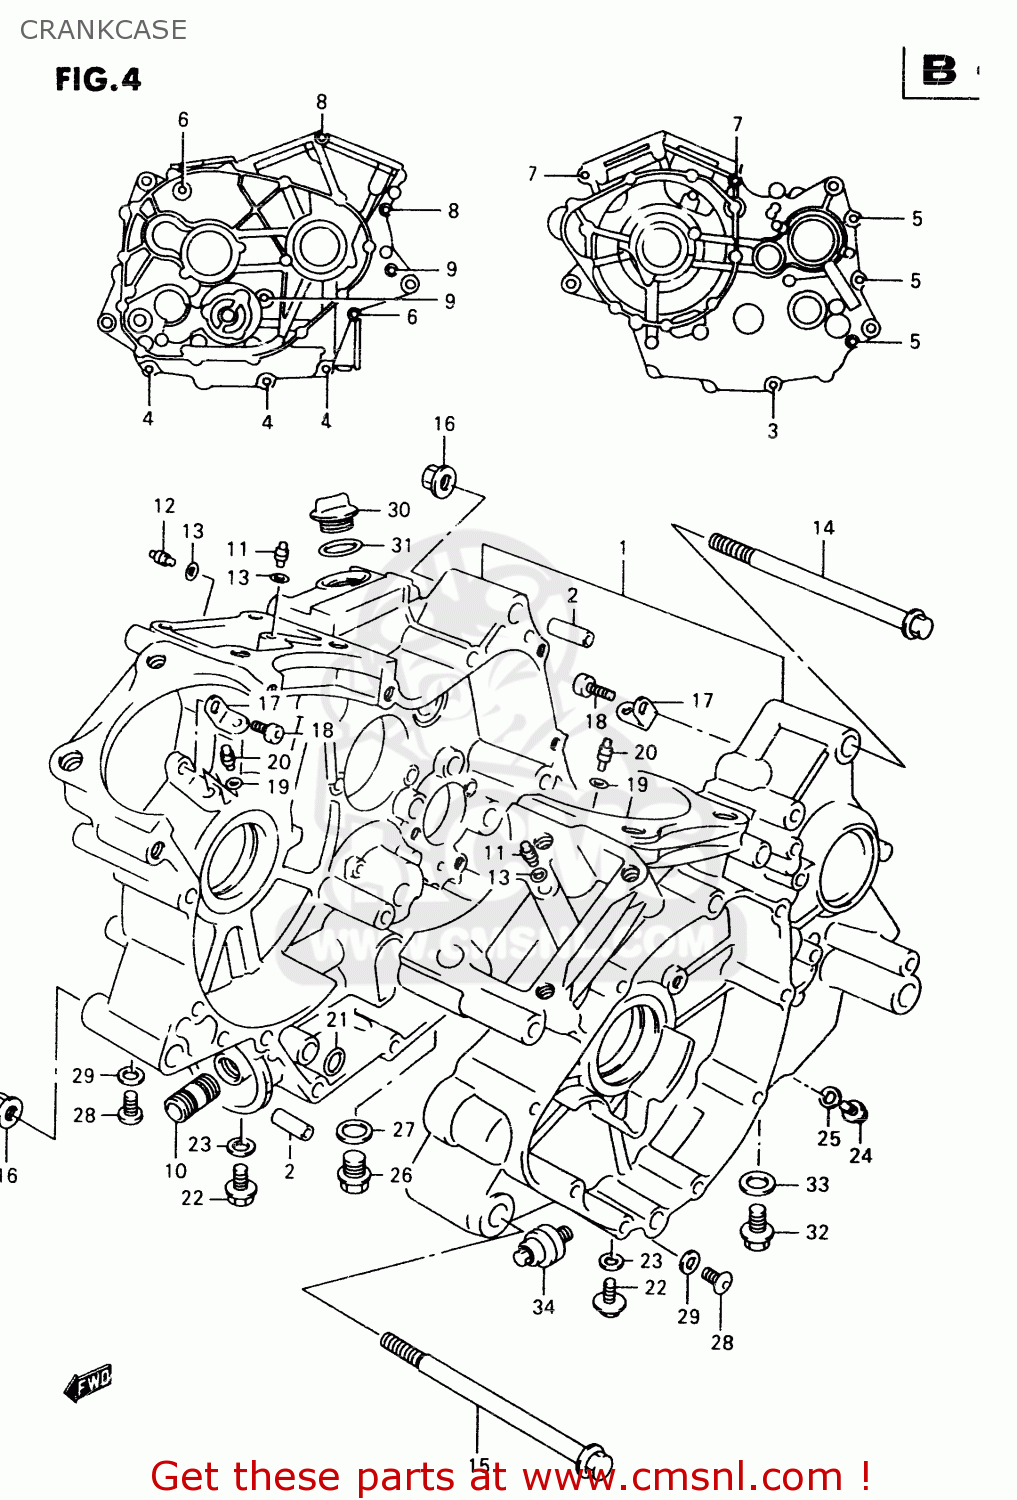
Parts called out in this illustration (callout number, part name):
1	CRANKCASE SET
2	PIN,CRANKCASE
3	BOLT
4	BOLT
5	BOLT
6	BOLT (8X70)
7	BOLT(8X105)
8	BOLT(8X160)
9	BOLT(8X80)
10	UNION,OIL STAND
11	JET,OIL GALLERY(18)
12	JET(8)
13	O RING(D:1.2,ID:4)
14	BOLT(10X143)
15	BOLT(10X155)
16	NUT
17	PLATE,PISTON COOLING JET
18	BOLT
19	O RING(D:1.2,ID:4)
20	JET,PISTON COOLING(0.8)
21	O RING(D:1.9,ID:12.6)
22	BOLT
23	GASKET(8.2X14X1).6 (NAS)
24	BOLT
25	GASKET(5.8X11X1.2) (NAS)
26	PLUG
27	GASKET(16X22X2) (NAS)
28	BOLT
29	GASKET(8.2X14X1).6 (NAS)
30	PLUG
31	O RING(D:3.1,ID:16.8)
32	BOLT
33	GASKET(12.1X16.2X3.7) (NAS)
34	SWITCH ASSEMBLY,OIL PRESSURE
